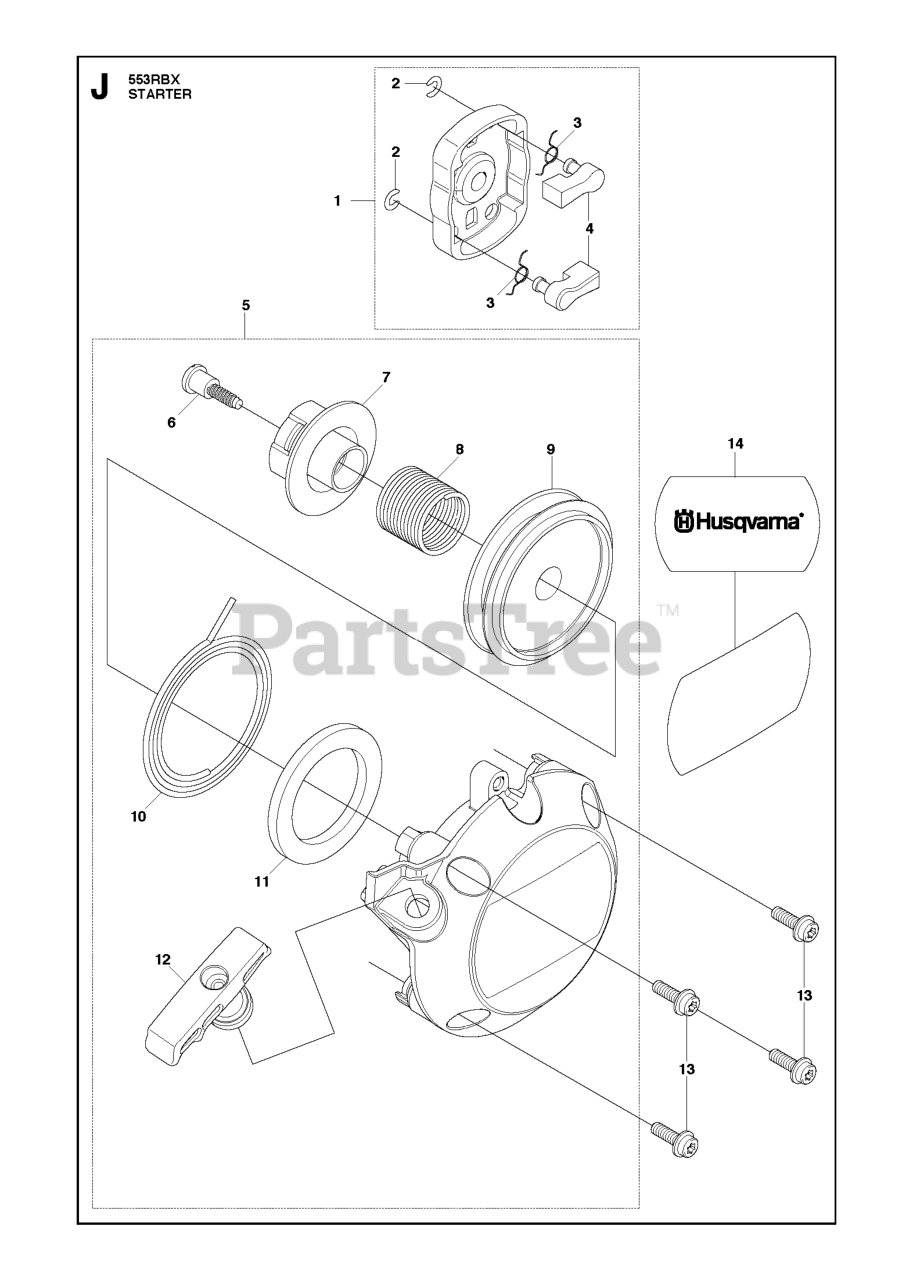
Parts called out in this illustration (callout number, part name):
2	E-RING
11	SPRING, SPIRAL
13	BOLT TORX
